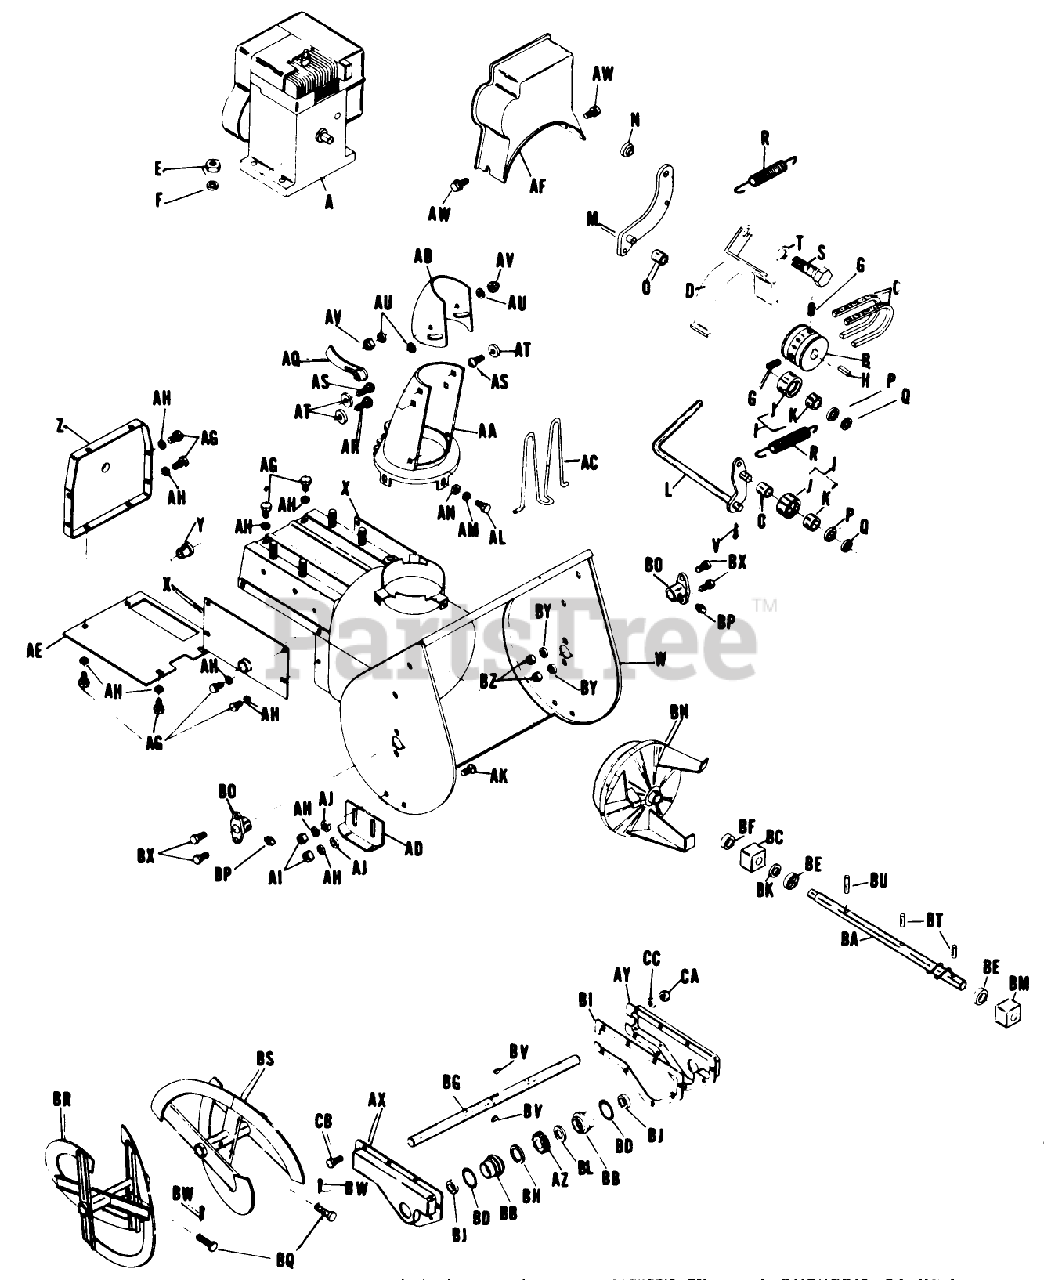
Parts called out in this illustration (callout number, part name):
A	Engine, 4 HP. BS Model 100202, Type 0434-01
D	Belt Guide
H	3/16 x 3/16 x 1 1/4 Key
W	Auger Wrap Main Frame Assembly
Z	Backing Plate Assembly
AA	Chute Ring Assembly
BG	Output Shaft
BR	Auger Assembly, R.H.
BS	Auger Assembly, L.H.
